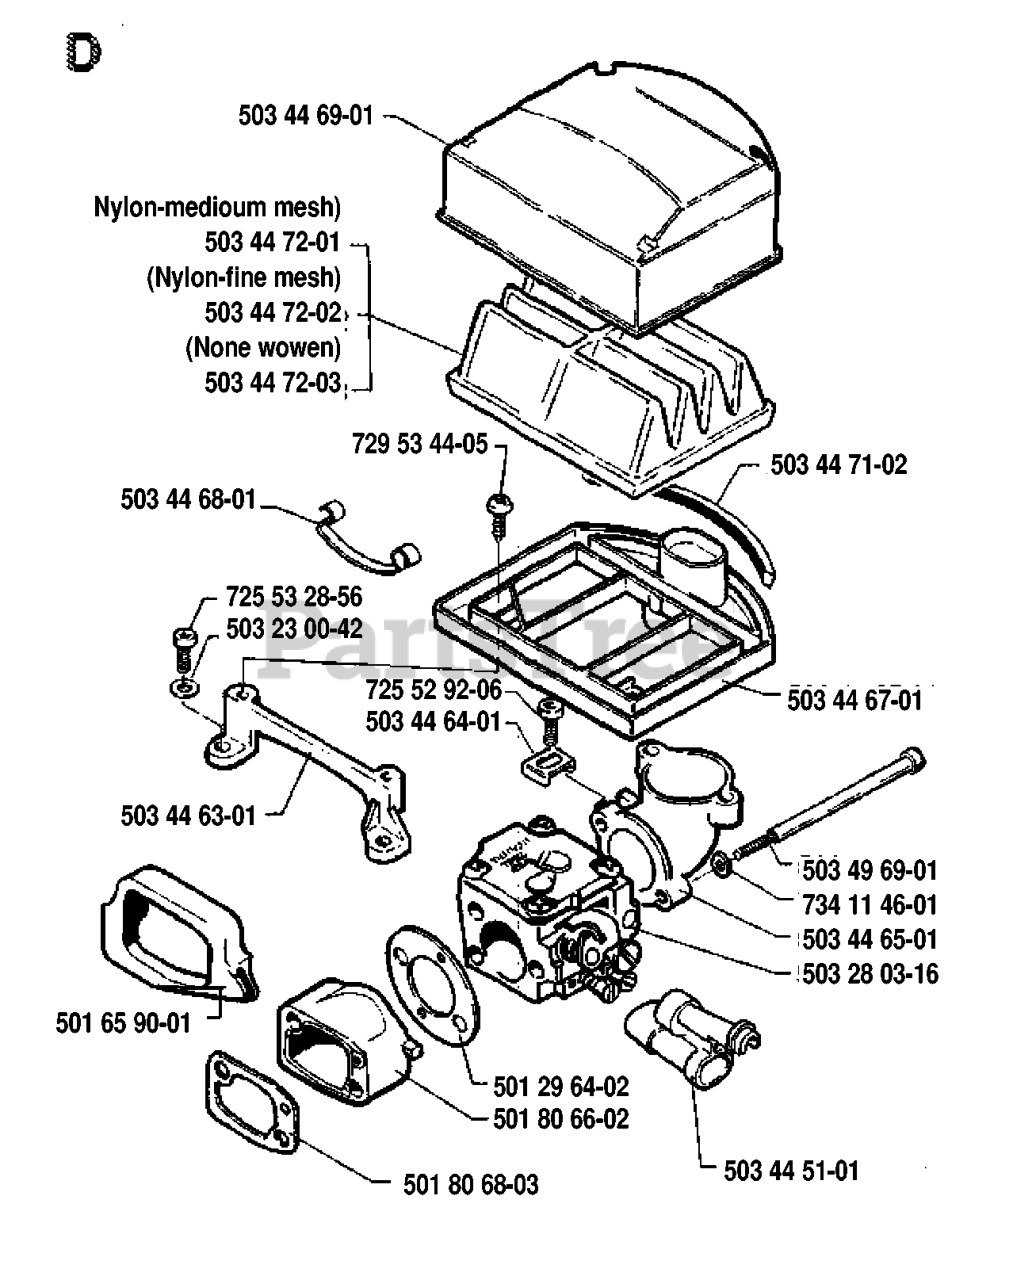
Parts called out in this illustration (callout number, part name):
3	NUT T
4	HANDLE.BAGGER.W/LVRS.BLK.CRD
5	SCREW.PAN.HEAD
6	REPL BY 532 75 00-29
8	COVER.PNT.BGR.CRD.WSLOTS.MS668
9	Bolt Carriage 1/4-20 x 2.25d x Gr.5
10	TUBE
11	BRACKET.SUPPORT.UPPER.BAG.CRD
12	BRKT PIVOT
14	BOLT-HEX EAK
15	RETAINER-SPRNG RB
16	NUT LOCK FLG 3/8-16 UNC
17	RP BOLT 5/16-18 X3/4 ZN/YEL GR
19	NUT LOCK HEX FLANGE 5/16-18
20	BRKT.PIVOT.RH.CRD
21	BAGGER.ASM.CRD.2007
22	BRACKET.BAGGER.SD.ELECTRIC.CRD
24	TUBE.PIVOT.BAG.CRD.BLACK
25	PIPE
33	MULCHING.PLUG.107.CRD.(2 2)
34	HANDLE.MULCHER.92.CRD (2 2)
36	WASHER
37	Plug Support Bagger CRD
38	BOLT.5/16-18X2.5
39	SEAL.BAGGER.CRD
41	BRKT.VERT.ADJ.BAGGER.CRD
46	BOLT.CARRIAGE.5/16-18
47	PIPE
49	ROD
50	NUT.71038.31-18.HEX.NYLOCK
51	LATCH
53	NUT
54	BOLT
57	BOLT
61	RETAINER M
69	WASHER
70	RIVET RIVET POP
